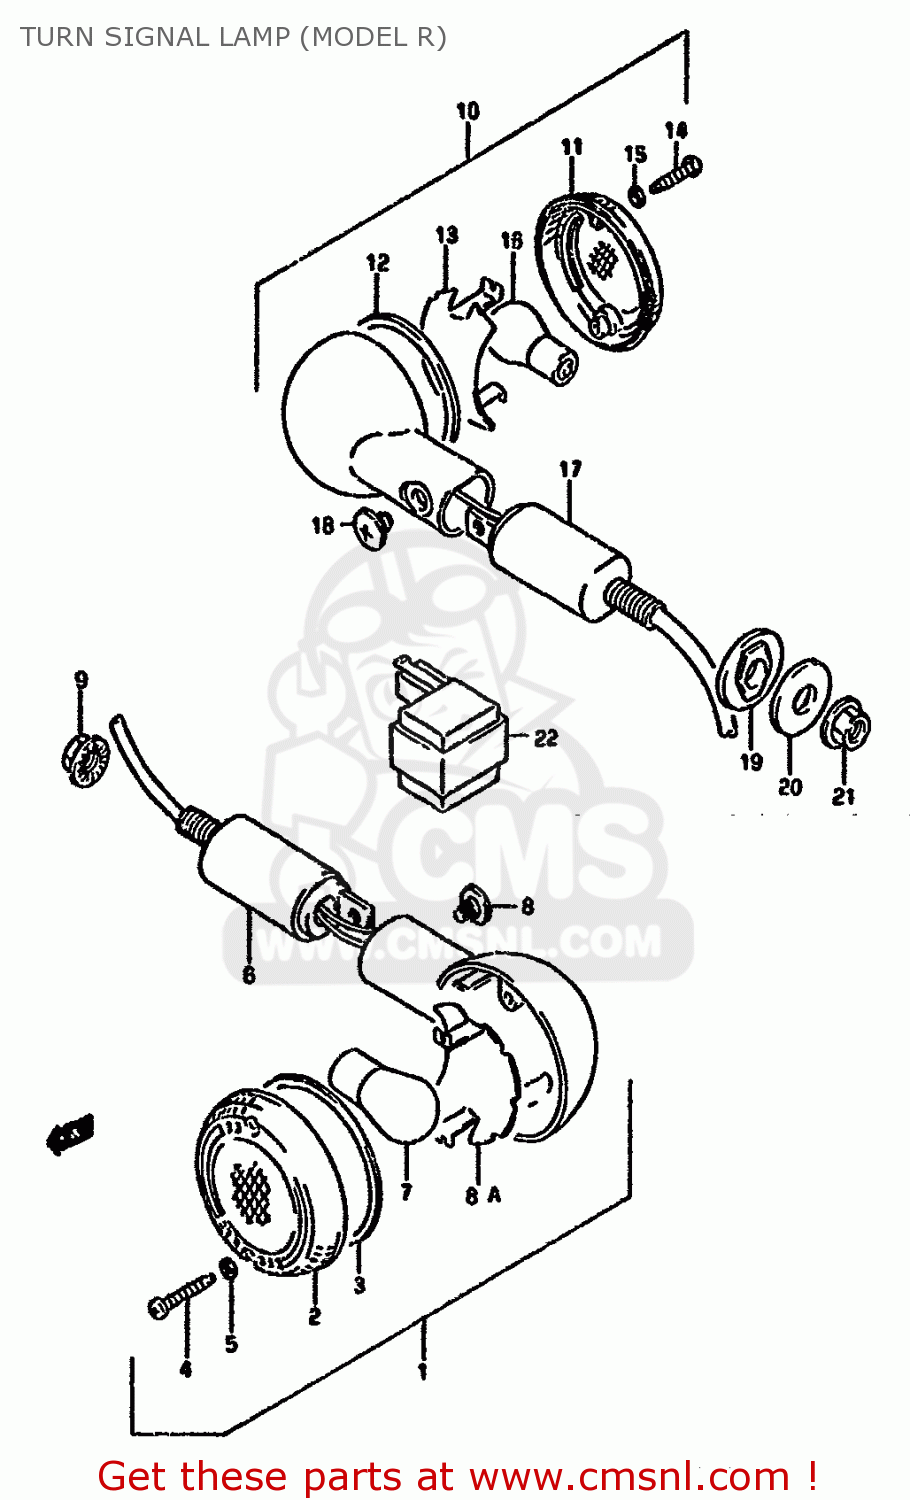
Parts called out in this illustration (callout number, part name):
1	LAMP ASSY,FR TURN SIGNAL
2	LENS
3	GASKET (NAS)
4	SCREW
5	GASKET (NAS)
6	STAY,TURNSIGNAL FR
7	BULB(12V21W)
8	SCREW
8A	REFLECTOR
9	NUT
10	LAMP ASSY,RR TURNSIGNAL,R
11	LENS
12	GASKET (NAS)
13	REFLECTOR
14	SCREW
15	GASKET (NAS)
16	BULB(12V21W)
17	STAY,TURNSIGNAL RR
18	SCREW
19	SPACER,RR TURNSIGNAL
20	WASHER(10.5X30X3.2)
21	NUT
22	RELAY ASSY,TUR
